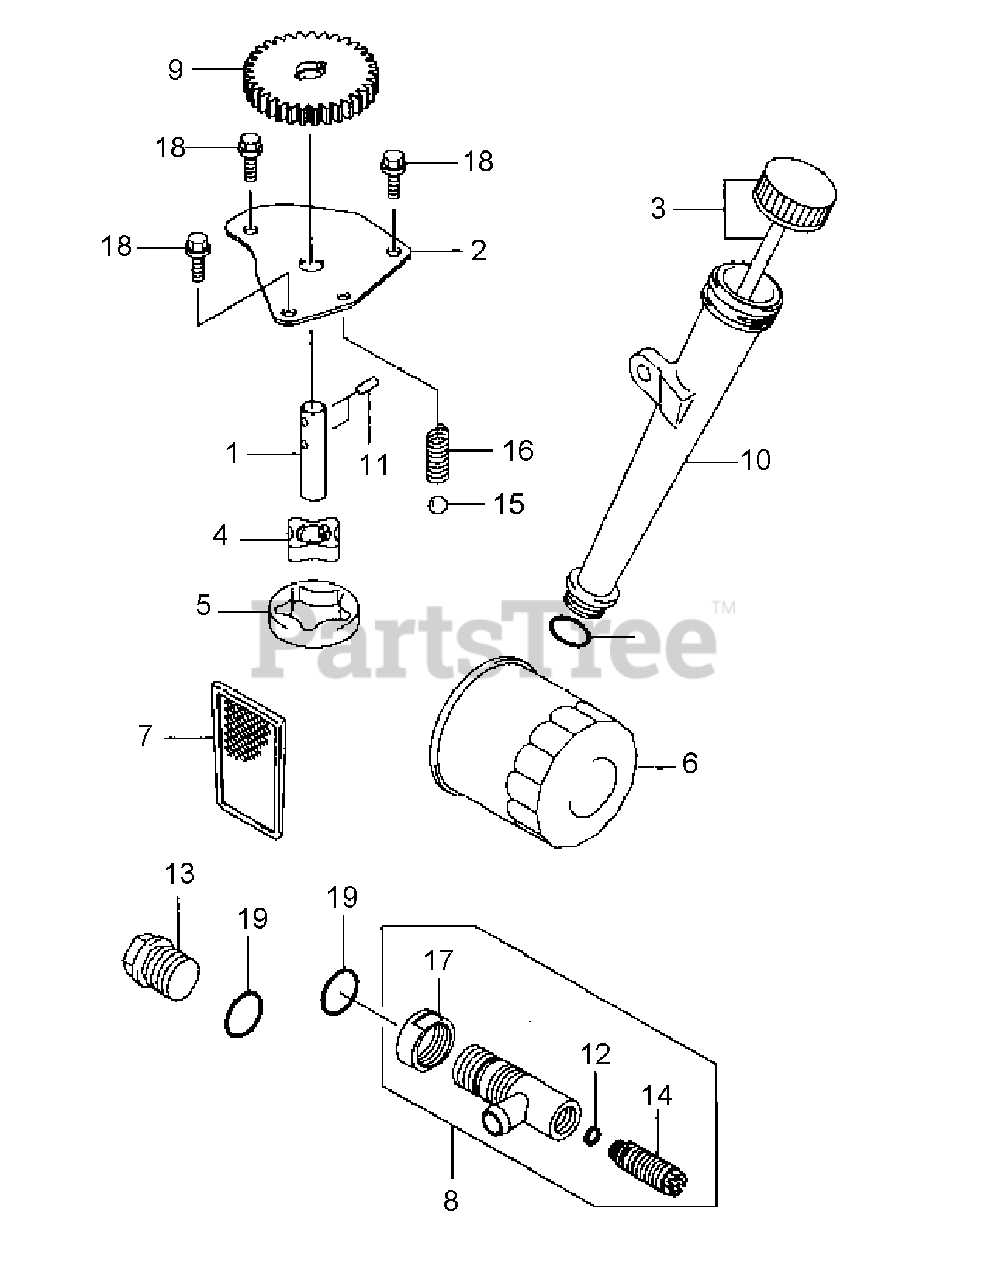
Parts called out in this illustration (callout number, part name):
1	SHAFT
3	CAP-ASSY
4	ROTOR-PUMP, IN
5	ROTOR-PUMP, OUT
6	FILTER-OIL
7	FILTER-OIL SCREEN
8	VALVE ASSY.
11	PIN
13	PLUG
14	PLUG
18	BOLT-FLANGED
19	O RING, 16MM
